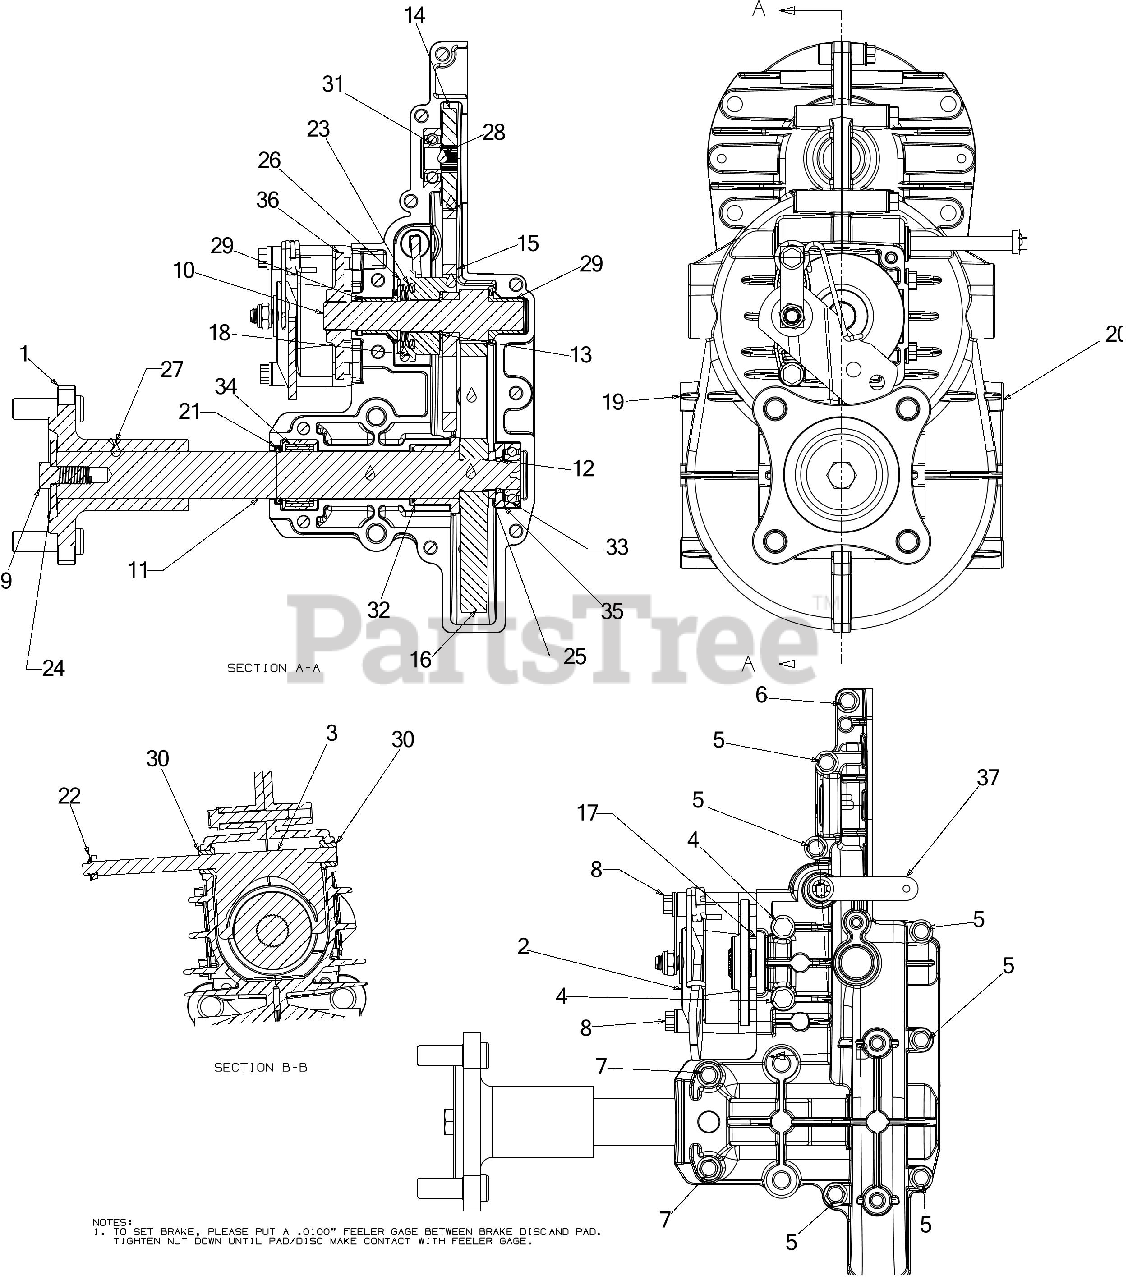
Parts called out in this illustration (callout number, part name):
1	WHEEL HUB ASSEMBLY
2	BRAKE ASSEMBLY (LH)
3	NEUTRAL DROP ACTUATOR
4	SCREW 1/4-20 x 2
5	SCREW 1/4-20 x 1.50"
6	SCREW 1/4-20 x 1.00
7	SCREW 1/4-20 x 1.25
8	SCREW 1/4-20 x 2.375
9	SCREW 3/8-16 x .75 GR 5
10	OUTPUT SHAFT 11T
11	AXLE SHAFT
12	SNAP RING
13	RETAINING RING
14	SPUR GEAR:22T
15	SPUR GEAR:53T:INPUT
16	SPUR GEAR 61T
17	BRAKE PUCK
18	U-TURN CLUTCH COLLAR
19	AXLE HOUSING
20	AXLE HOUSING
21	AXLE SEAL 1.0X1.25X.125
22	PUSH NUT:1/4 x 17/32
23	SPRING-1.00 x 1.375 X.400
24	FLAT WASHER .390x1.500x.134
25	FLAT WASHER .632X1.00X.16
26	FLAT WASHER .635X1.585X.062 HDN
27	ANTI-SIEZE (NOT SERVICEABLE)
28	GREASE (NOT SERVICEABLE)
29	FLANGE BEARING
30	SLOTTED FLANGE BEARING
31	SEALED BALL BEARING
32	FLANGE BEARING
33	BALL BEARING
34	NEEDLE BEARING
36	BRAKE DISC
37	LEVER PLATE
